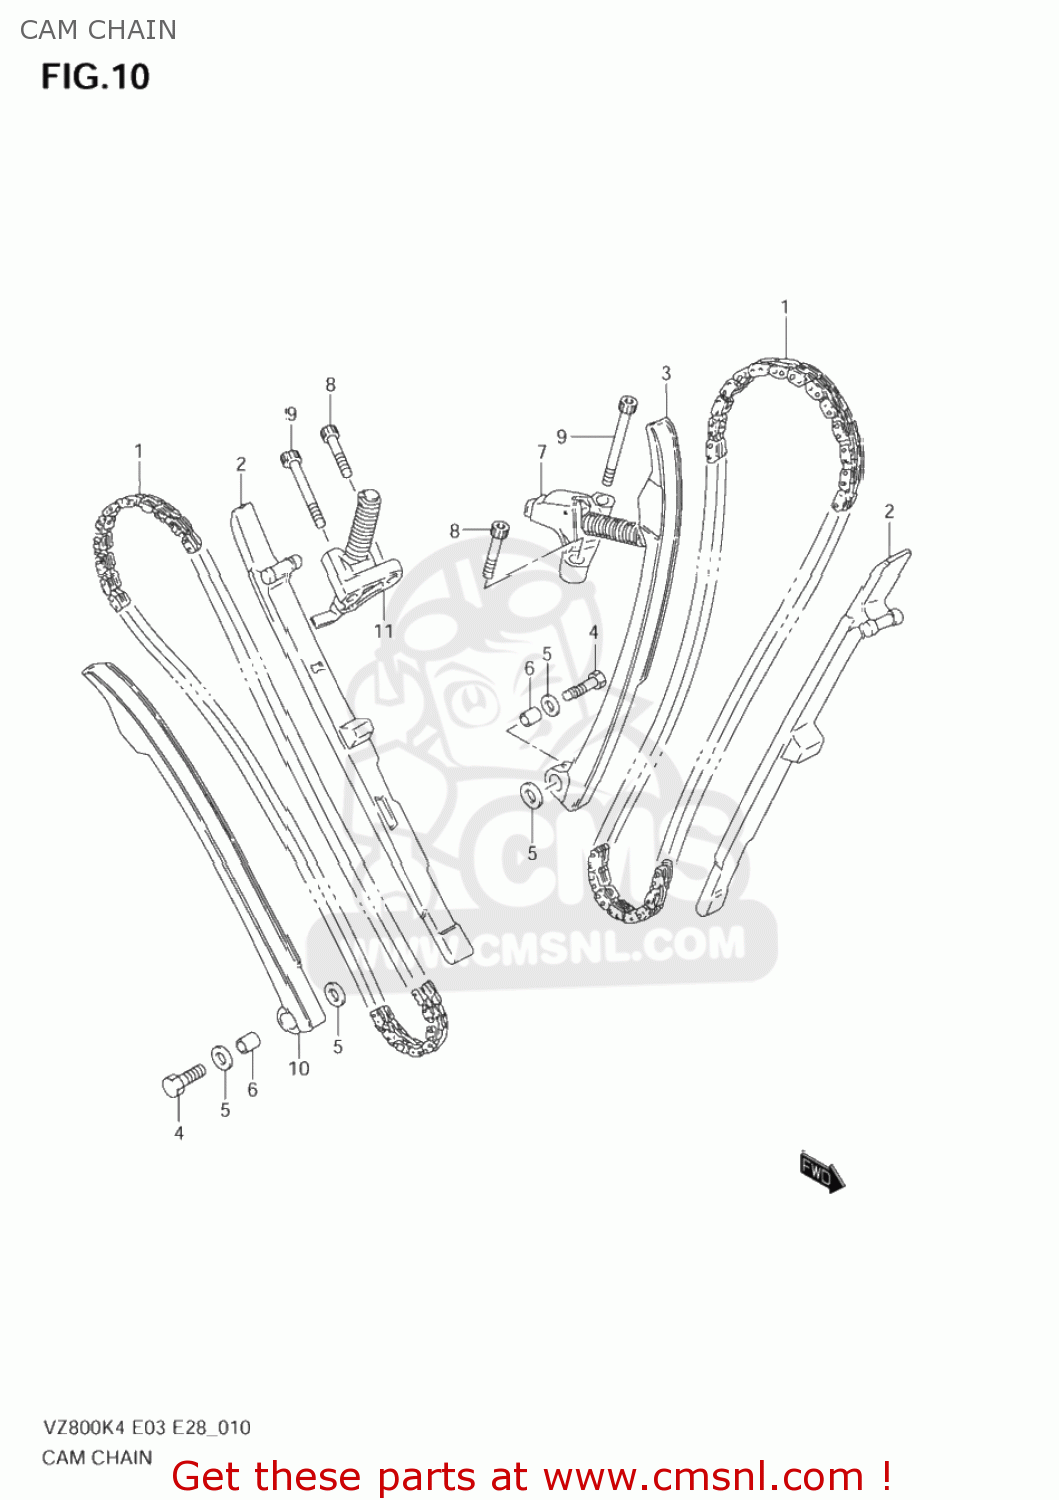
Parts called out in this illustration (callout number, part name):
1	CHAIN,CAMSHAFT DRIVE
2	GUIDE,CAM CHAIN
3	TENSIONER,FR CAM CHAIN
4	BOLT(6X26)
5	WASHER
6	SPACER(6X11X11)
7	ADJUSTER ASSEMBLY,FRONT TENSIONER
8	BOLT,CRKCASE,R
9	BOLT
10	TENSIONER,RR CAM CHAIN
11	ADJUSTER ASSEMBLY,REAR TENSIONER
